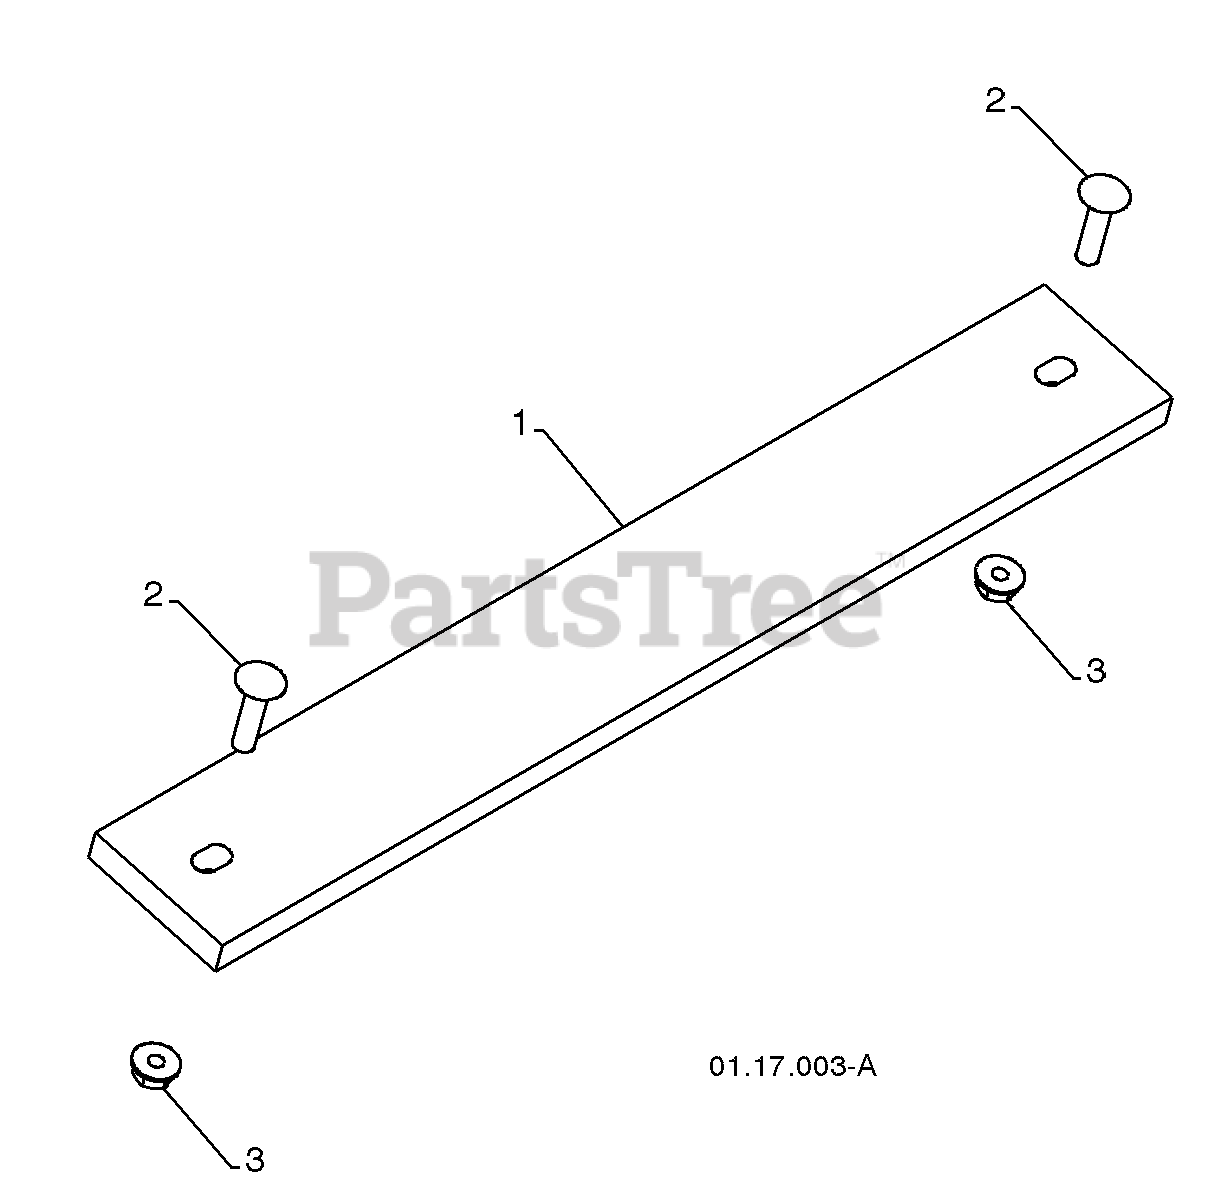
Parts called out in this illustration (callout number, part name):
1	WEIGHT BAR
2	CARRIAGE BOLT 5/16-18 X 1.25
3	NUT 5/16-18
